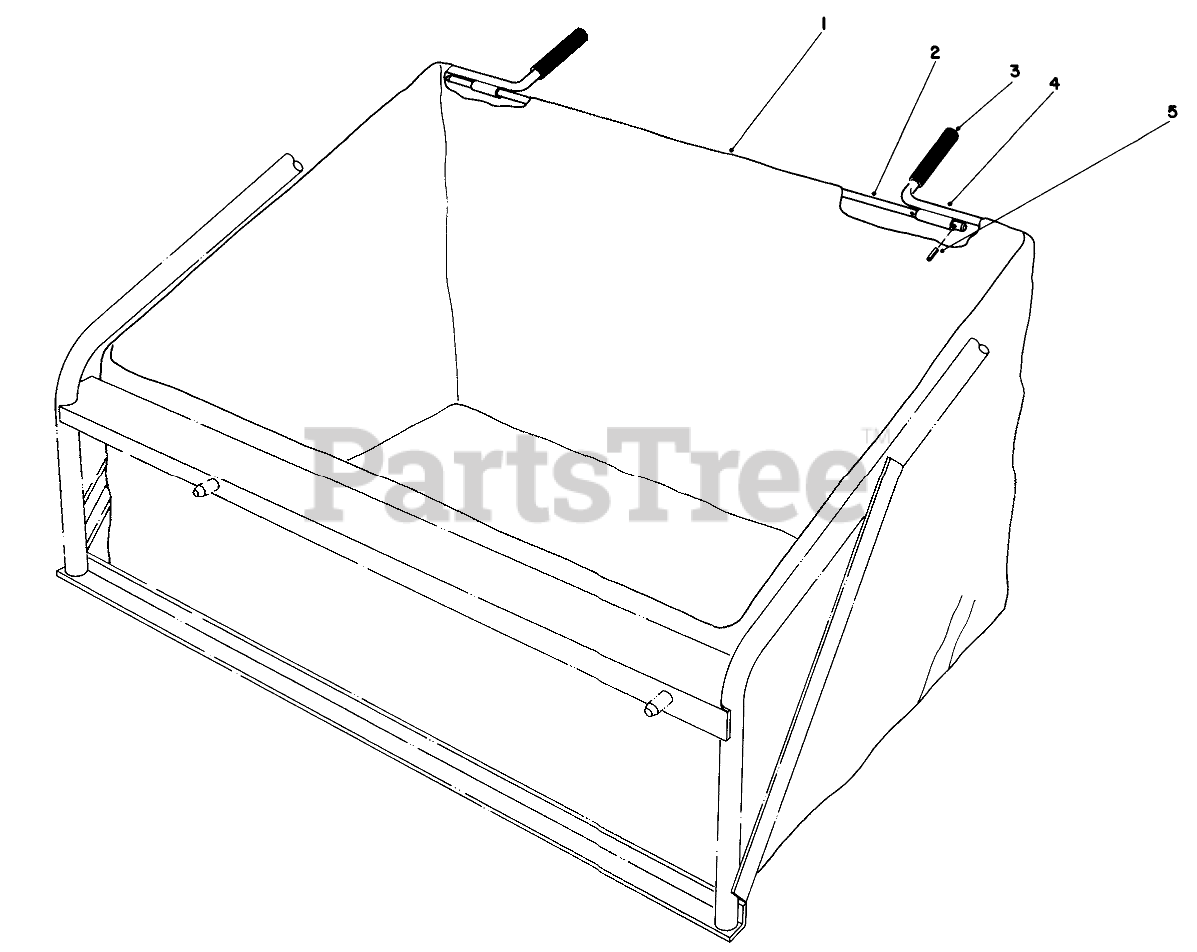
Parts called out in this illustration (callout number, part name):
1	Bag-Leaf Catcher
2	Rod-Bag Frame
3	BAG HANDLE GRIP
4	BAG FRAME WA B
5	PIN-ROLL
